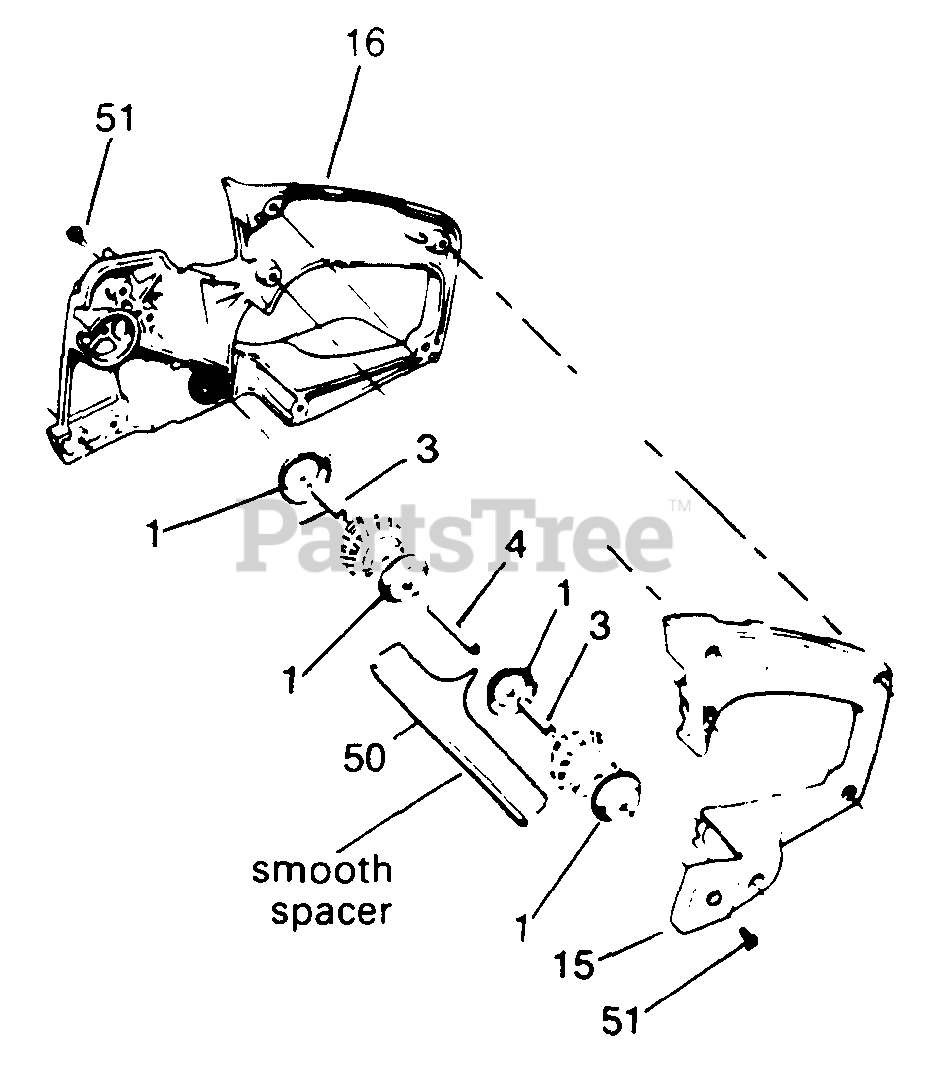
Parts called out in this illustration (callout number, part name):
1	Cup Isolator
3	Spacer Isolator
4	Spacer Isolator
6	Handle Brace
6	Handle Brace Use on Guide Bar Powerhead
6	Handle Brace Use on Bow Guide Powerhead
7	Screw - 10-24 x 9/16 Fil. Hd.
15	Rear Handle - Left
16	Rear Handle - Right
50	Pin - Rear Isolator
51	Screw - 10-24 x 3/8 Pan Head
